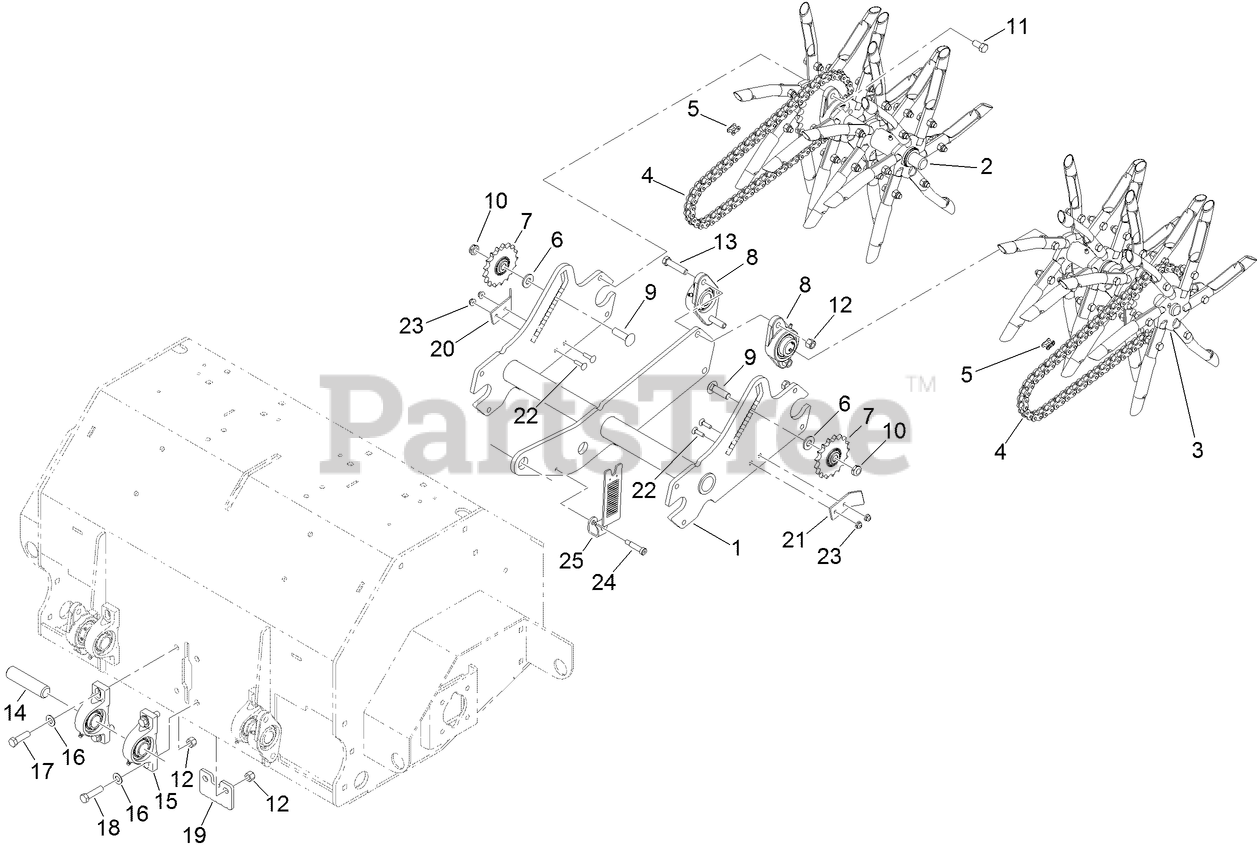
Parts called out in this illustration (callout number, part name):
1	ARM-TRAIL
2	ASM-TINE WHEEL, RH
3	ASM-TINE WHEEL, LH
4	CHAIN-ROLLER
5	LINK-CONNECTING
6	WASHER-THRUST
7	SPROCKET-IDLER, 15T
8	BEARING-FLANGE, 2 BOLT
9	SCREW-CARR
10	NUT-HEX
11	SCREW-HH
12	NUT-LOCK, NI
13	SCREW-HH
15	BEARING-PILLOW BLOCK
16	WASHER-FLAT
17	SCREW-HH
18	SCREW-HH
19	PLATE-DOWNSTOP
20	GUARD-CHAIN, RH
21	GUARD-CHAIN, LH
22	SCREW-CARR
23	NUT-HF
24	SCREW-HSH
25	BRACKET-CONTROL, DEPTH
